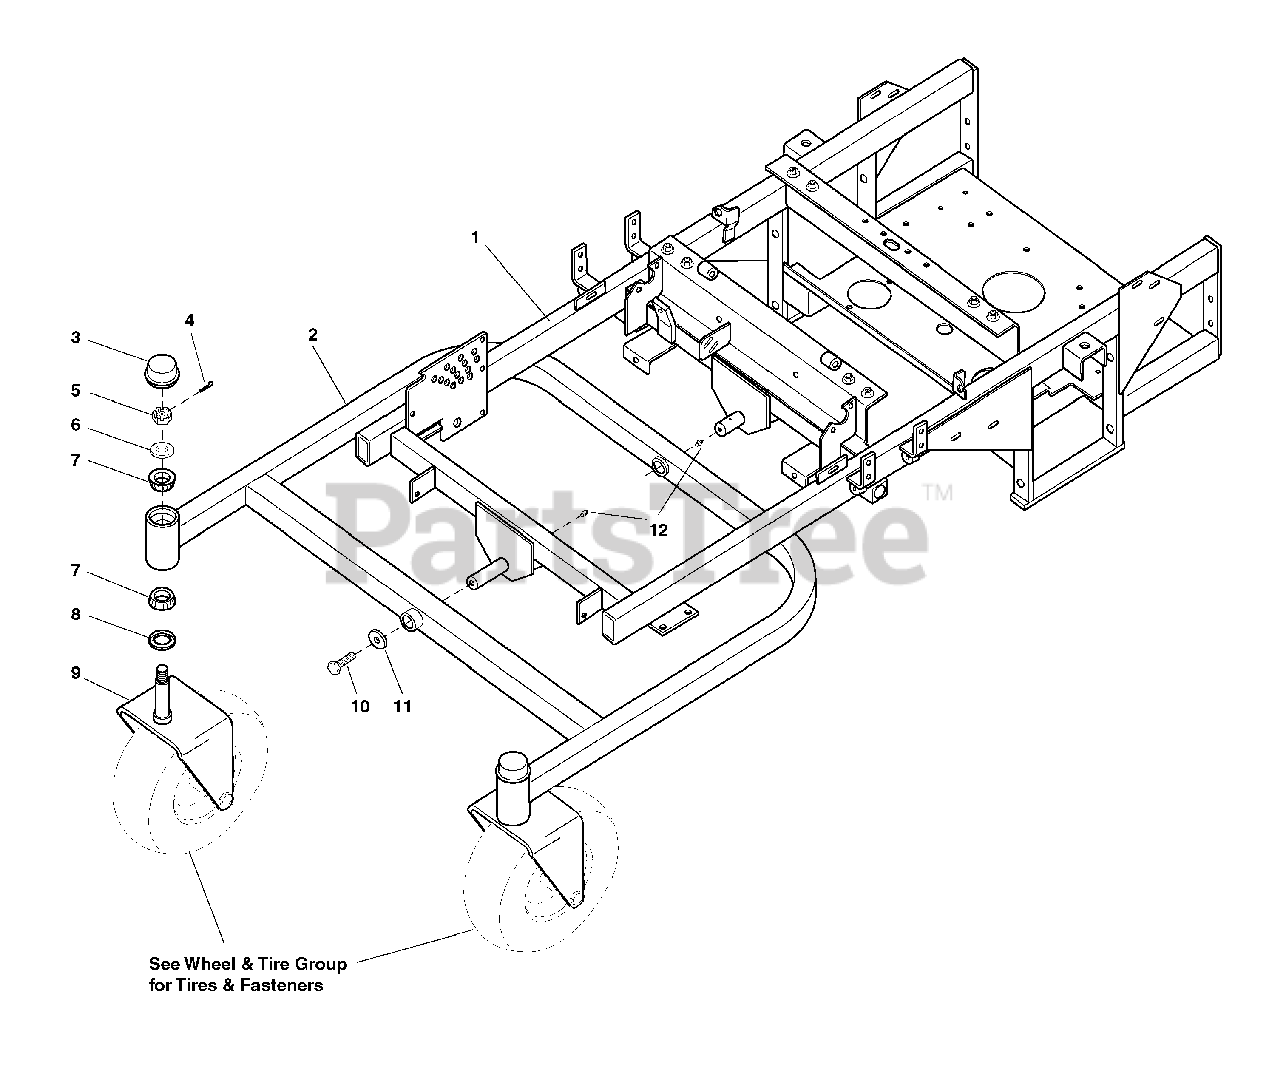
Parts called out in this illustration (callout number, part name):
1	MAIN FRAME
2	FRONT PIVOT FRAME
5	NUT, Hex, Slotted, 3/4-16
6	WASHER, 3/4
7	BEARING, Tapered Roller
8	SEAL, Grease
9	YOKE, Caster
10	CAPSCREW, Hex Hd, 1/2-20 x 1-1/4
11	RETAINER, Frame
12	GREASE FITTING
